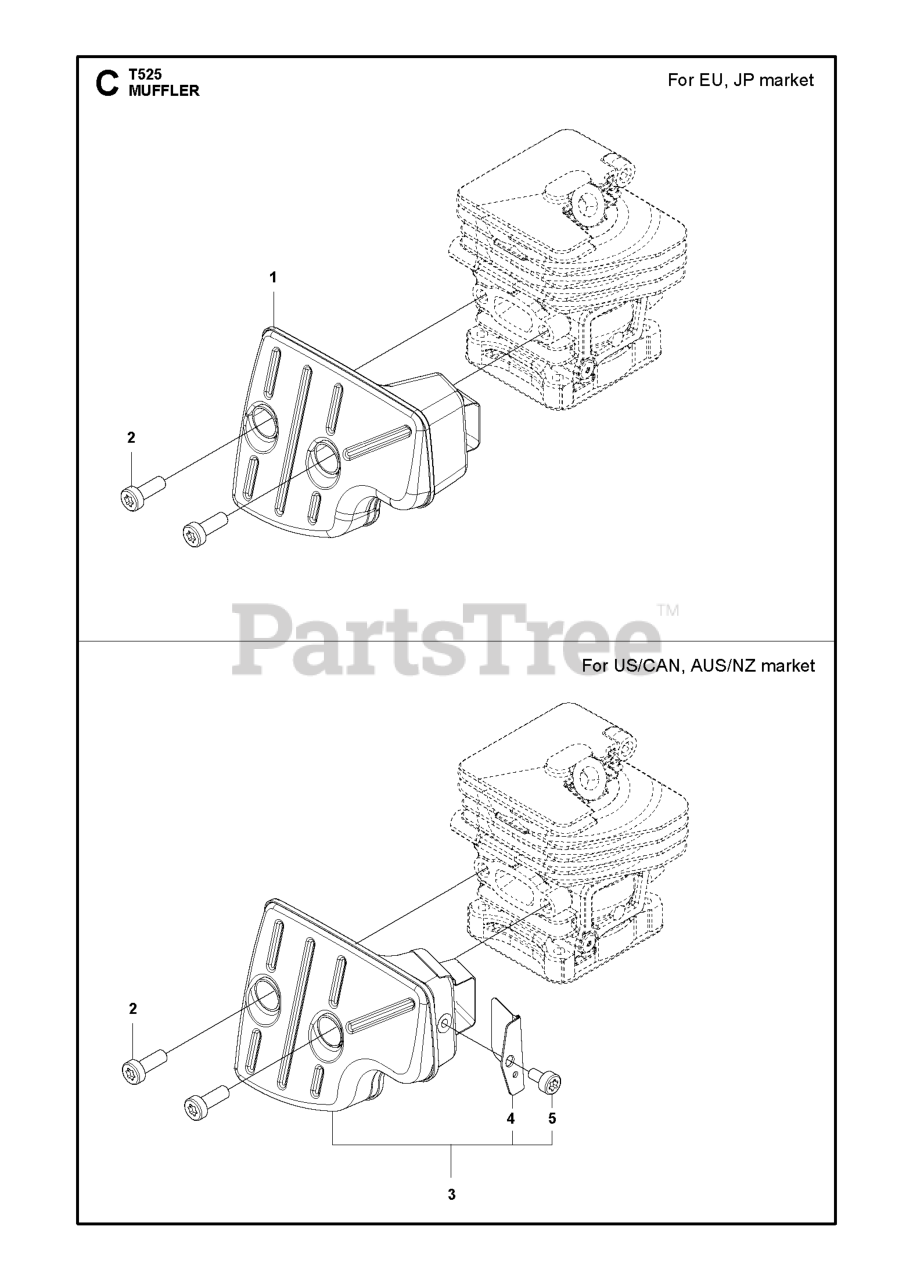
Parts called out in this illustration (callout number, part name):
1	MUFFLER COMP
3	MUFFLER ASSY
4	SPARK ARRESTER SCREEN
5	BOLT
